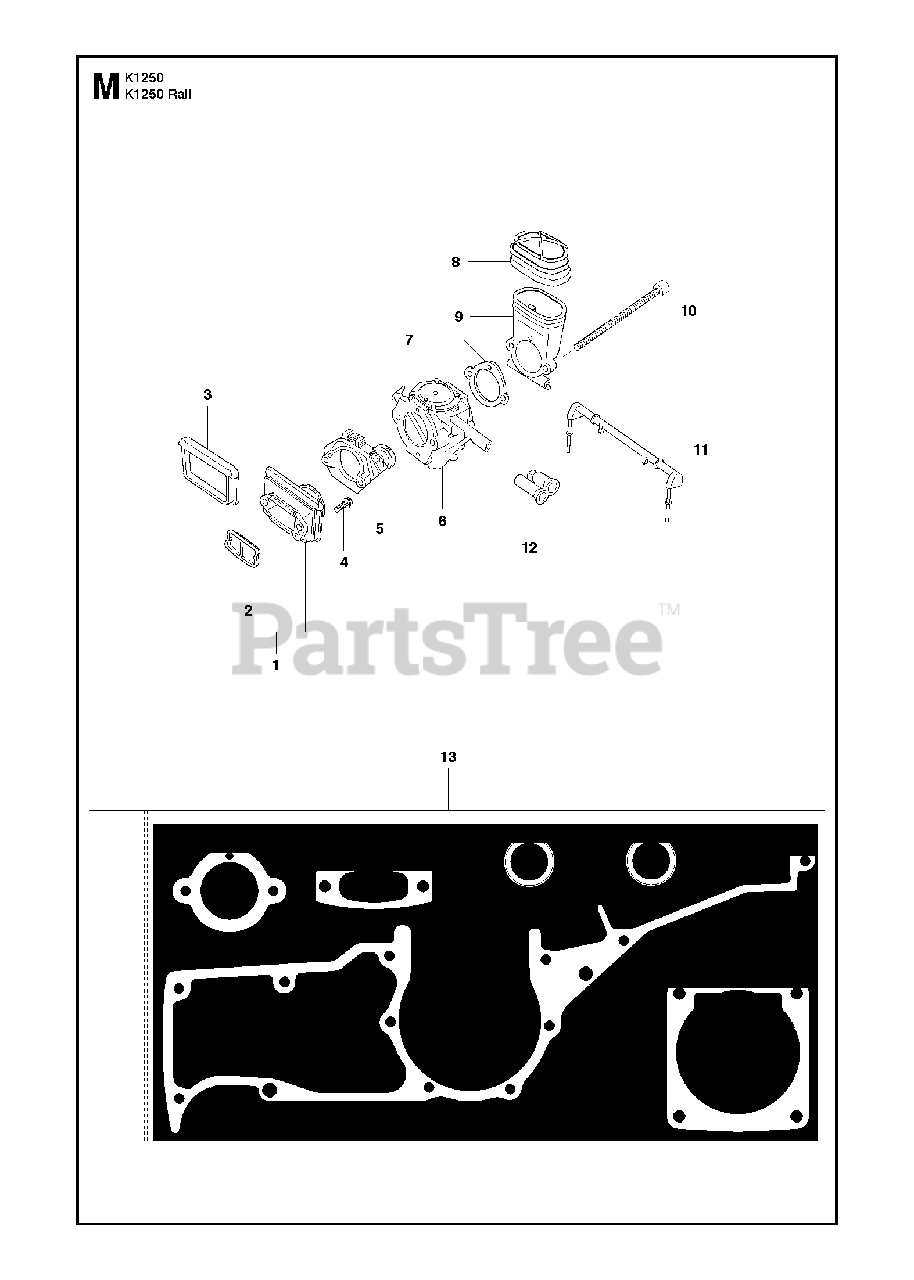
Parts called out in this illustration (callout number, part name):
1	FLANGEIncl. 2
4	SCREW IHSCFM
6	CARBURETTOR
7	GASKETGasket kit 13
10	SCREW IHSCFT
12	CHISEL GUIDE
13	GASKET KITIncl. 7, 14 - 17
14	GASKET
15	SEALING RING
